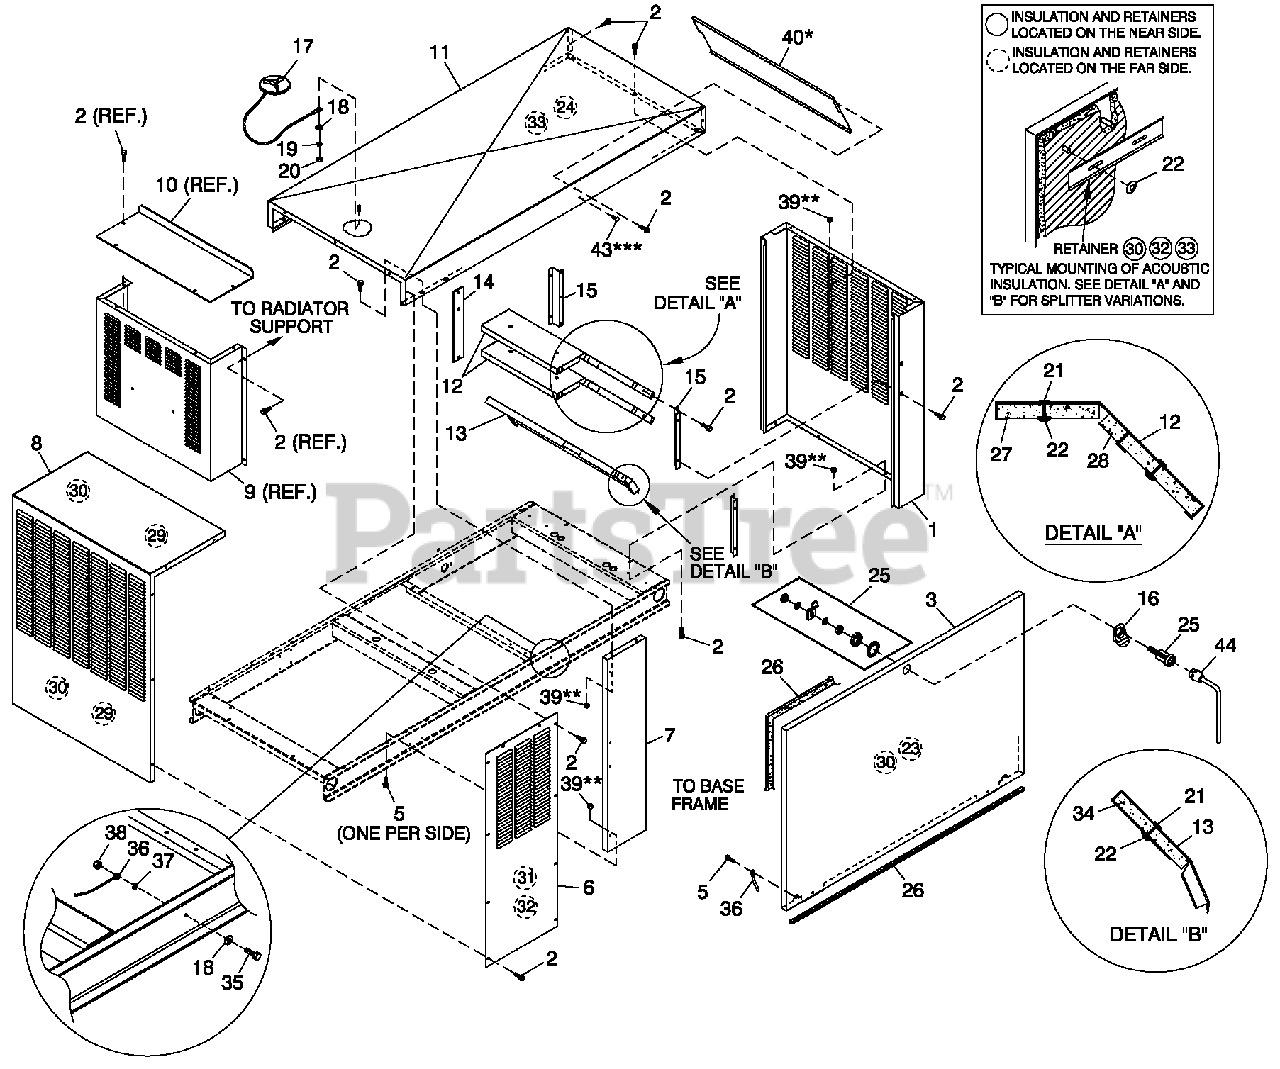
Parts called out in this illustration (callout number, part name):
1	REAR WRAP C2
2	SCREW THF M6-1 X 16 N WA Z/JS
3	DOOR C2
4	RIVET POP .1875 X .450 SS
5	SCREW TH-FRM M6 W/CAP SHKPRF W
6	DISCHARGE DUCT LH & RH SIDE C2
7	FRONT CORNERS C2
8	DISCHARGE CENTER DUCT C2
9	DUCT INNER DISCHARGE C2
10	DUCT INNER DISCHARGE TOP C2
11	ROOF C2ALUM
12	SLITTER C4
13	SPLITTER LOWER C4
14	SPLITTER STINGER C2
15	SUPPORT SPLITTER LHC2
16	TAB PULL
17	ASSEMBLY COVER ACCESS
18	WASHER FLAT 1/4-M6 ZINC
19	WASHER LOCK M6-1/4
20	NUT HEX 1/4-20 STEEL
21	INSULATION RETAINMENT HANGER
22	WASHER SELF LOCKING DOME
23	INSULATION DOOR C2
24	INSULATION ROOFTOP
25	VISE-ACTION LATCH SLOTTED CIR
26	GASKET EXTRUDED TRIM (328” LG)
27	INSULATION SPLITTER
28	INSULATION SPLITTER
29	INSULATION DUCT
30	RETAINER INSULATION (820)
31	INSULATION DUCT SIDES
32	RETAINER INSULATION (450)
33	RETAINER INSULATION (740)
34	INSULATION LOWER SPLITTER
35	SCREW HHC M6-1.0X 20 G8.8
36	ASSY WIRE 14AWG 34.8" GRN/YEL
37	WASHER SHAKEPROOFINT 1/4
38	NUT HEX M6 X 1.0 G8 YEL CHR
39	NUT HEX LOCK M6-1.0 SS NY INS
40	ROOF RAIN DEFLECTOR
43	FASTENER RATCHET
44	KEY VISE-ACTION LATCH SLOT CIR
